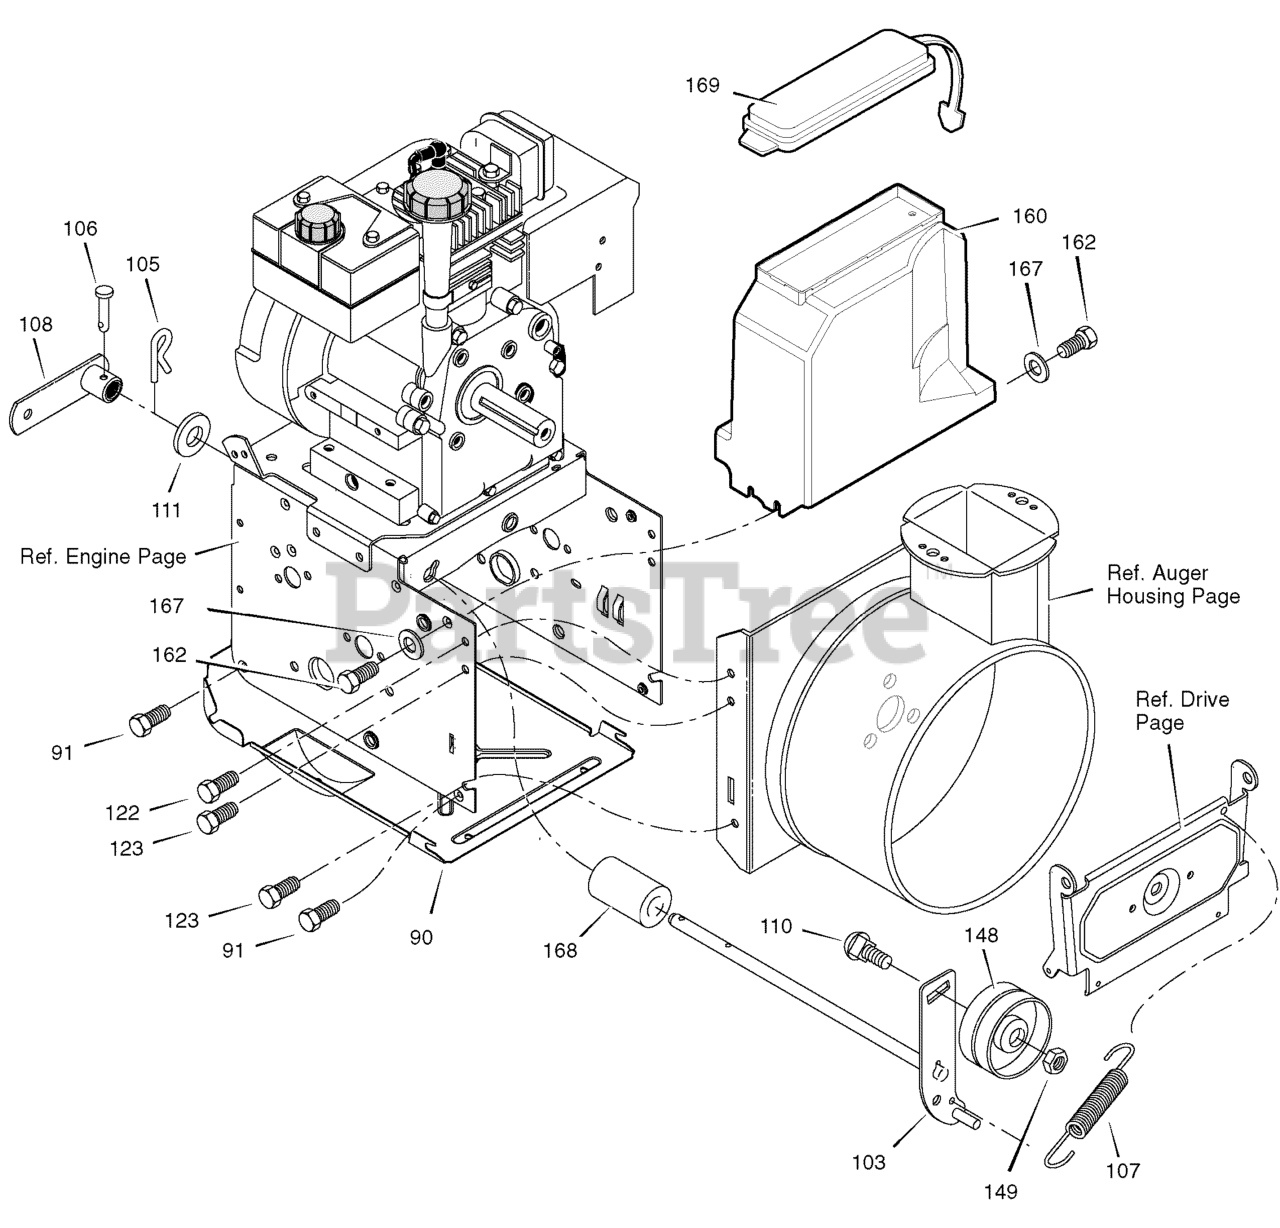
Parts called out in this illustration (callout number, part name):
90	COVER, BOTTOM
91	SCREW, 1/4-20X .63
103	IDLER ASSEMBLY, AUGER
105	PIN, HAIR .38DIAX1.64LG
106	PIN, CLEVIS 3/16" DIA
107	SPRING, TENSION
108	ASSY., SPRING ATTACH
110	BOLT, 3/8-16X1.25 CARR.
111	WASHER, FLAT
122	SCREW, TAP 5/16-18 X .75
123	SCREW, TAP 5/16-18 X .50
148	PULLEY, IDLER
149	NUT, JAM 3/8-16
160	COVER, BELT
162	SCREW, TAP
167	WASHER, FLAT
168	SPACER, AUGER BRACKET
169	LID, TOOL BOX
